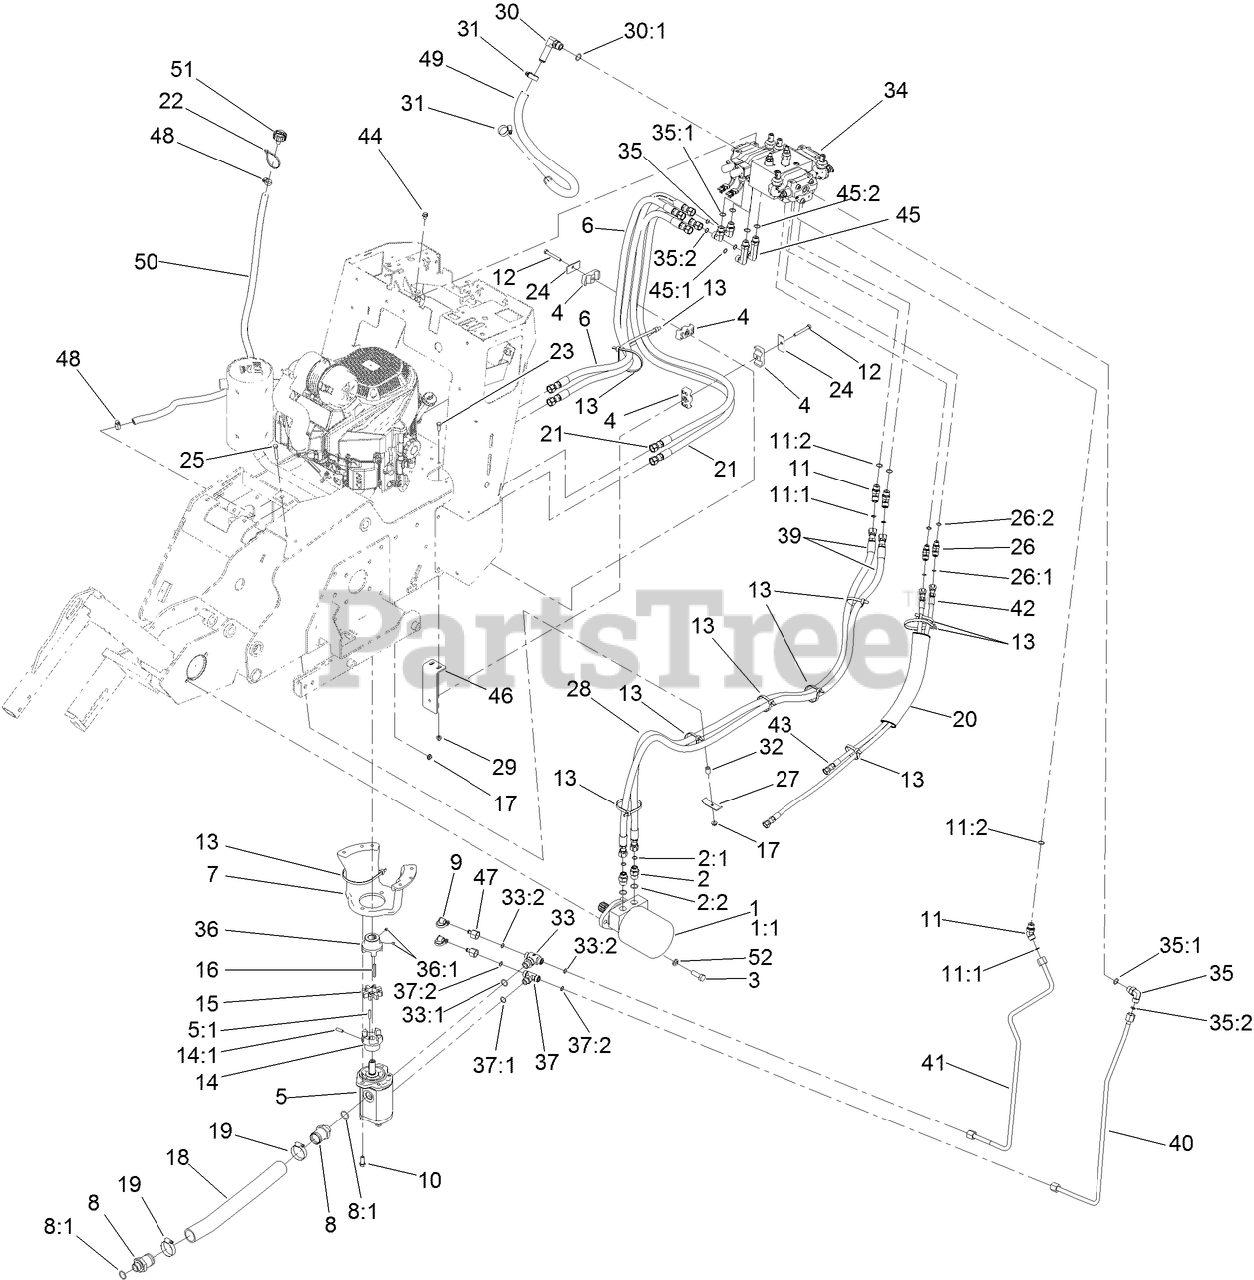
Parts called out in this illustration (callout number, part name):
1	HYDRAULIC MOTOR ASM
1:1	SEAL KIT
2	FITTING-STRAIGHT
2:1	O-RING
2:2	O-RING
3	SCREW-HH
4	CLAMP-TUBE
5	PUMP-HYD
5:1	KEY-SQUARE
6	HYDRAULIC HOSE ASM
7	MOUNT-PUMP
8	FITTING-STR
8:1	O-RING
9	CAP-DUST
10	SCREW-HH
11	FITTING-HYD, 45 DEG
11:1	O-RING
11:2	O-RING
12	SCREW-HH
13	TIE-CABLE
14	COUPLER-FLEX
14:1	SCREW-SET
15	COUPLER-SPIDER
16	KEY-SQUARE
17	NUT-HF
18	HOSE-SUCTION, HYD
19	CLAMP-HOSE
20	SLEEVE-PROTECTIVE
21	HYDRAULIC HOSE ASM
22	TIE-CABLE
23	SCREW-HH
24	PLATE-COVER
25	SCREW-HH
26	FITTING-ELBOW, 45 DEG
26:1	O-RING
26:2	O-RING
27	BRACKET-CLAMP
28	SLEEVE-PROTECTIVE
29	NUT-HF, NI
30	FITTING-90
30:1	O-RING
31	CLAMP-HOSE
32	SPACER
33	FITTING-HYD
33:1	O-RING
33:2	O-RING
34	VALVE ASM
35	FITTING-ELBOW, 90 DEG
35:1	O-RING
35:2	O-RING
36	HUB-FLEX (1.125" SHAFT)
36:1	SCREW-SET
37	FITTING-HYD, TEE
37:1	O-RING
37:2	O-RING
39	HYDRAULIC HOSE ASM
40	HYD TUBE ASM
41	HYD TUBE ASM
42	HYDRAULIC HOSE ASM
43	HOSE-HYD
44	SCREW-HHF
45	FITTING-ELBOW 90 LONG
45:1	O-RING
45:2	O-RING
46	BRACKET-SUPPORT, HOSE
47	FITTING
48	CLAMP-HOSE
49	HOSE-COOLER
50	HOSE-BREATHER
51	BREATHER
52	WASHER-LOCK
